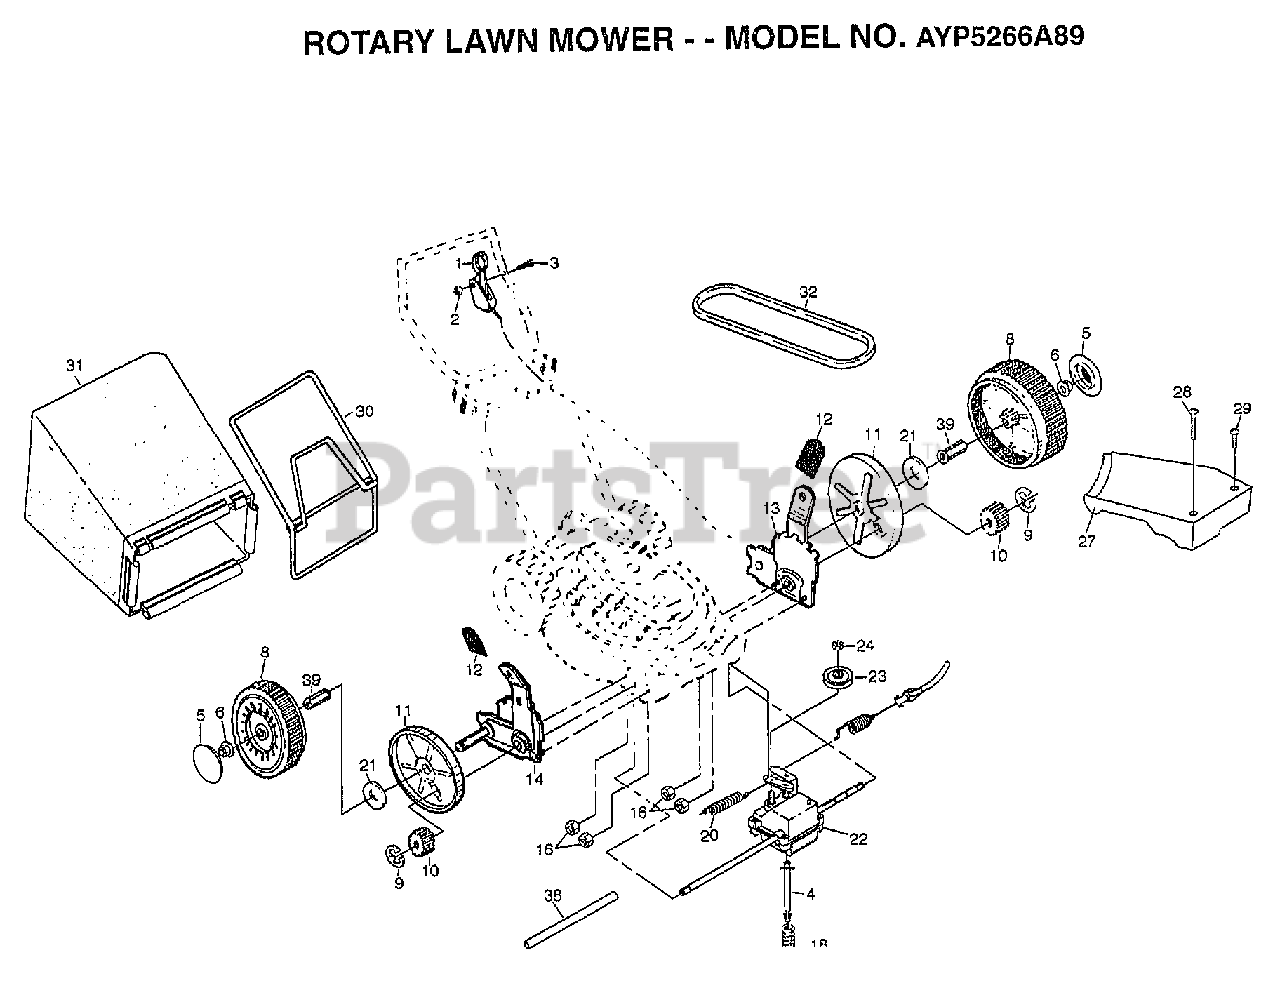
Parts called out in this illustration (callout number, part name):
1	CONTROL.DRV.56.25
2	LOCKNUT
3	PAN HEAD SCREW
4	SPRING.RETAINER.
5	HUB CAP
6	NUT.HXFLG.LOCK.
8	WHEEL.8X2.LP.PR
9	E-RING.7/16.RE.
10	PINION.GEAR
11	DUST SHROUD PM
12	KNOB PM
13	WHEEL.ADJ.ASM.LH.
14	WHEEL.ADJ.ASM.RH.
18	SPRING.TENSION
20	SPRING
21	WASHER FLUT
23	PULLEY.DRIVEN
24	LOCKNUT
27	"COVER.DRIVE 22""RD"
28	SCREWL.SLOT.TORXT
29	SCREW.SLOT.TORTX.
30	FRAME.CATCHER.2.5
31	GRASSBAG.250B1.BL
38	DRV SHAFT TUBE PM
39	BUSHING.HEX
